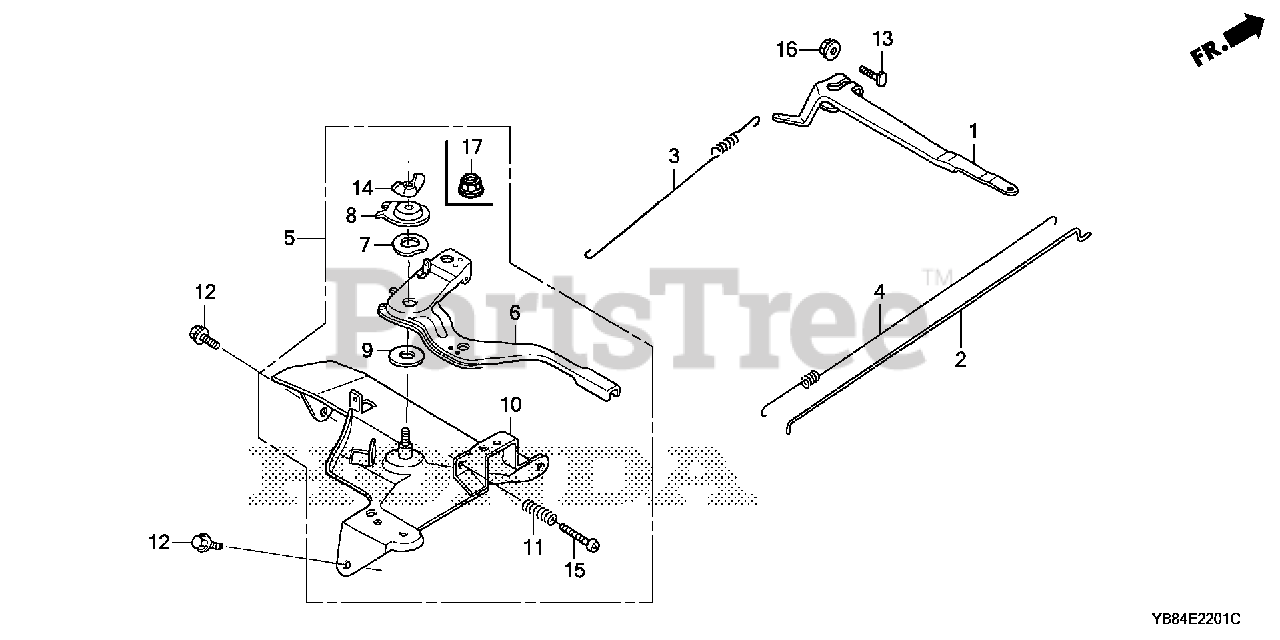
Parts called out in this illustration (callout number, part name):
1	ARM, GOVERNOR
2	ROD, GOVERNOR
3	SPRING, GOVERNOR (L=145.0MM) (WIRE DIAMETER 1.0MM)
4	SPRING, THROTTLE RETURN
5	CONTROL ASSY.
6	LEVER, CONTROL
7	SPRING, LEVER
8	WASHER, CONTROL LEVER
9	SPACER, CONTROL LEVER
10	BASE, CONTROL
11	SPRING, CONTROL ADJUSTING
12	BOLT, FLANGE (6X12) (CT200)
13	BOLT, GOVERNOR ARM
15	SCREW, PAN (5X28)
16	NUT, FLANGE (6MM)
17	NUT, SELF-LOCK (6MM)
